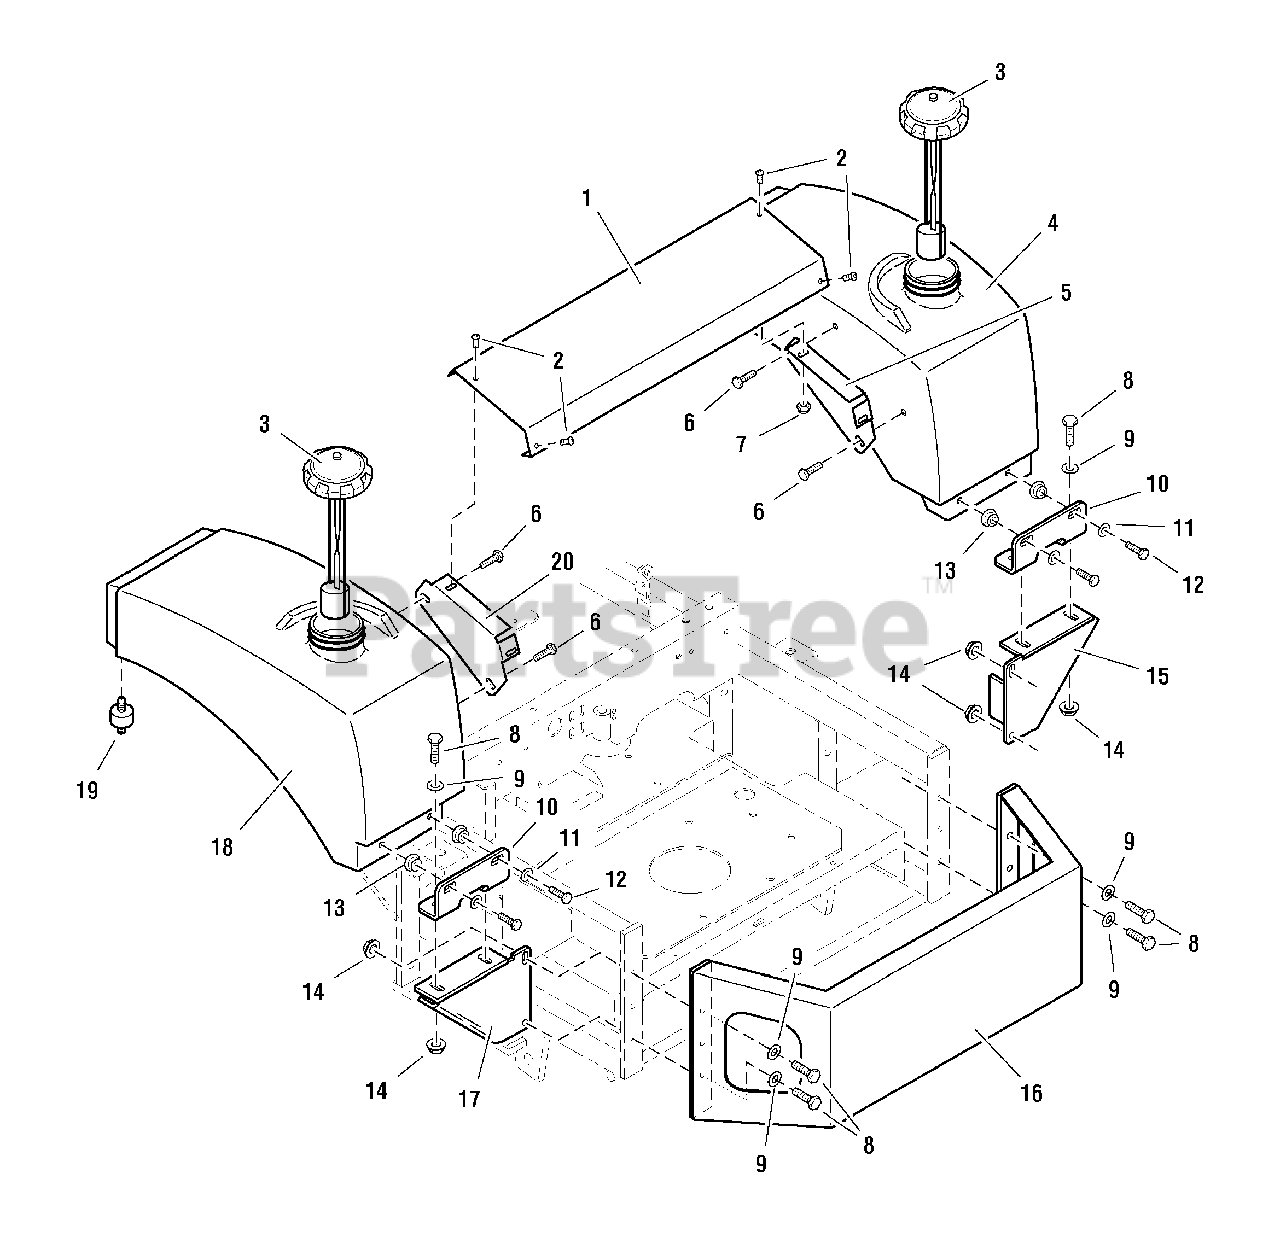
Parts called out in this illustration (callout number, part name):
1	FUEL TANK TIE BAR
2	SCREW, Allan Hd, 1/4-20 x 3/4
3	CAP, Fuel Tank w/ Gauge
4	FUEL TANK-RH, Complete (see footnote)
5	TIE BAR MOUNT-RH
6	CAPSCREW, Hex Hd, 5/16-18 x 3/4
7	NUT, Hex, Nylon Lock, 1/4-20
8	CAPSCREW, Hex Hd, 3/8-16 x 1
9	WASHER, 3/8
10	REAR MOUNT BRACKET
11	WASHER, 5/16
12	CAPSCREW, Hex Hd, 5/16-18 x 1-1/4
13	RUBBER BUSHING
14	NUT, Hex, Serrated Flange, 3/8-16
15	TANK MOUNT-RH
17	TANK MOUNT-LH
18	FUEL TANK-LH, Complete (see footnote)
19	RUBBER ISOLATOR
20	TIE BAR MOUNT-LH
